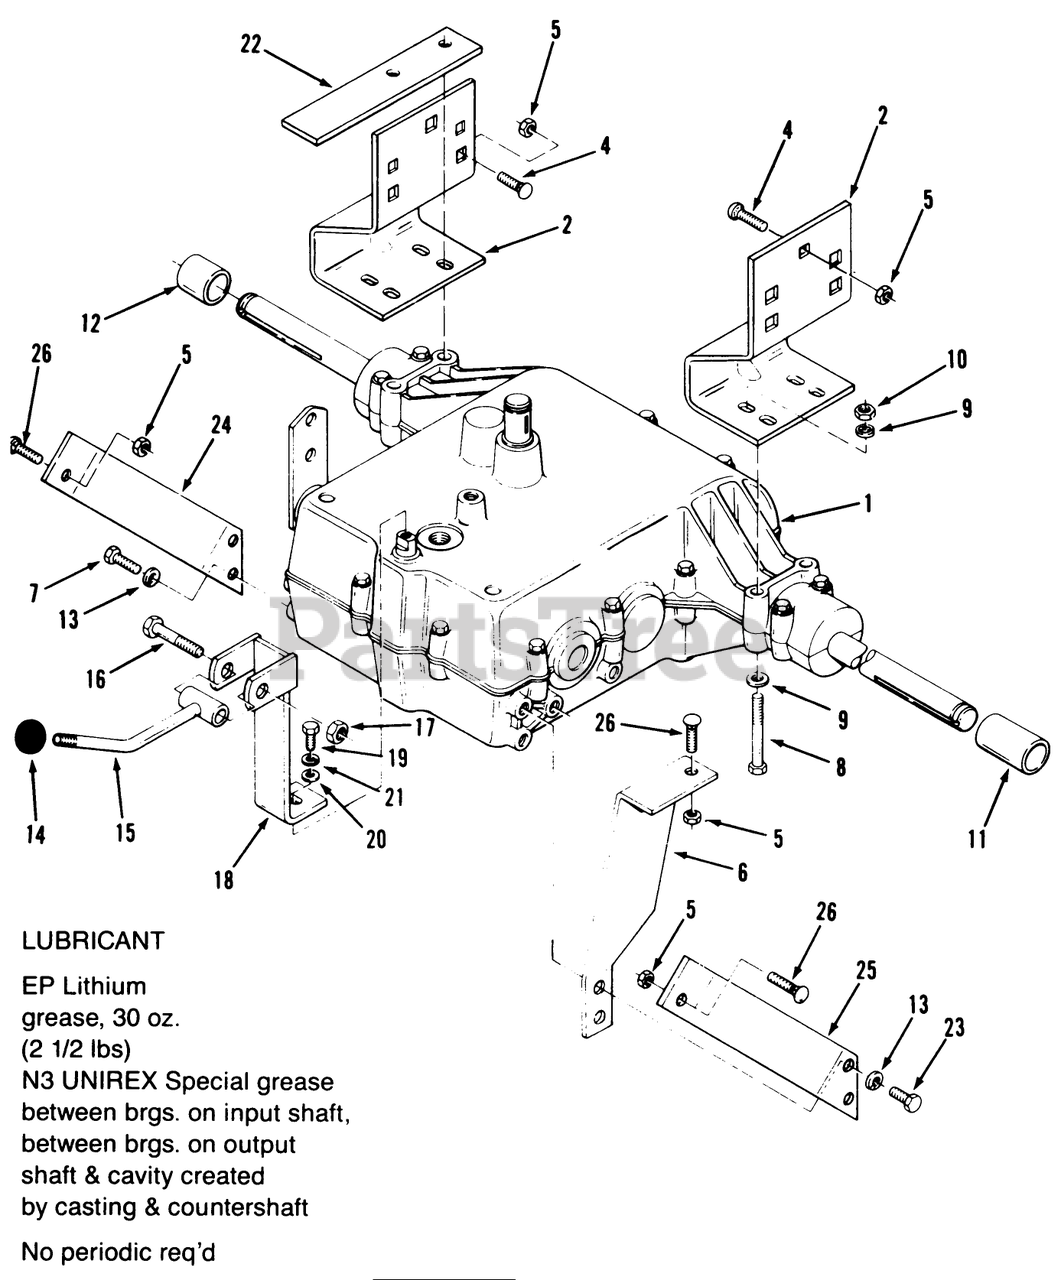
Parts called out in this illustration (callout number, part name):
1	Transmission-5-Speed Peerless Model 801-026
4	SCREW-HH
5	NUT-HEX
6	TORQUE STRAP
7	Screw
8	SCREW-HH
9	WASHER-PLAIN
10	NUT-HEX
13	WASHER-LOCK
16	SCREW-HH
17	NUT-LOCK, NI
18	ASSY LEVER *R
20	WASHER
21	WASHER-LOCK
26	BOLT-CARR
